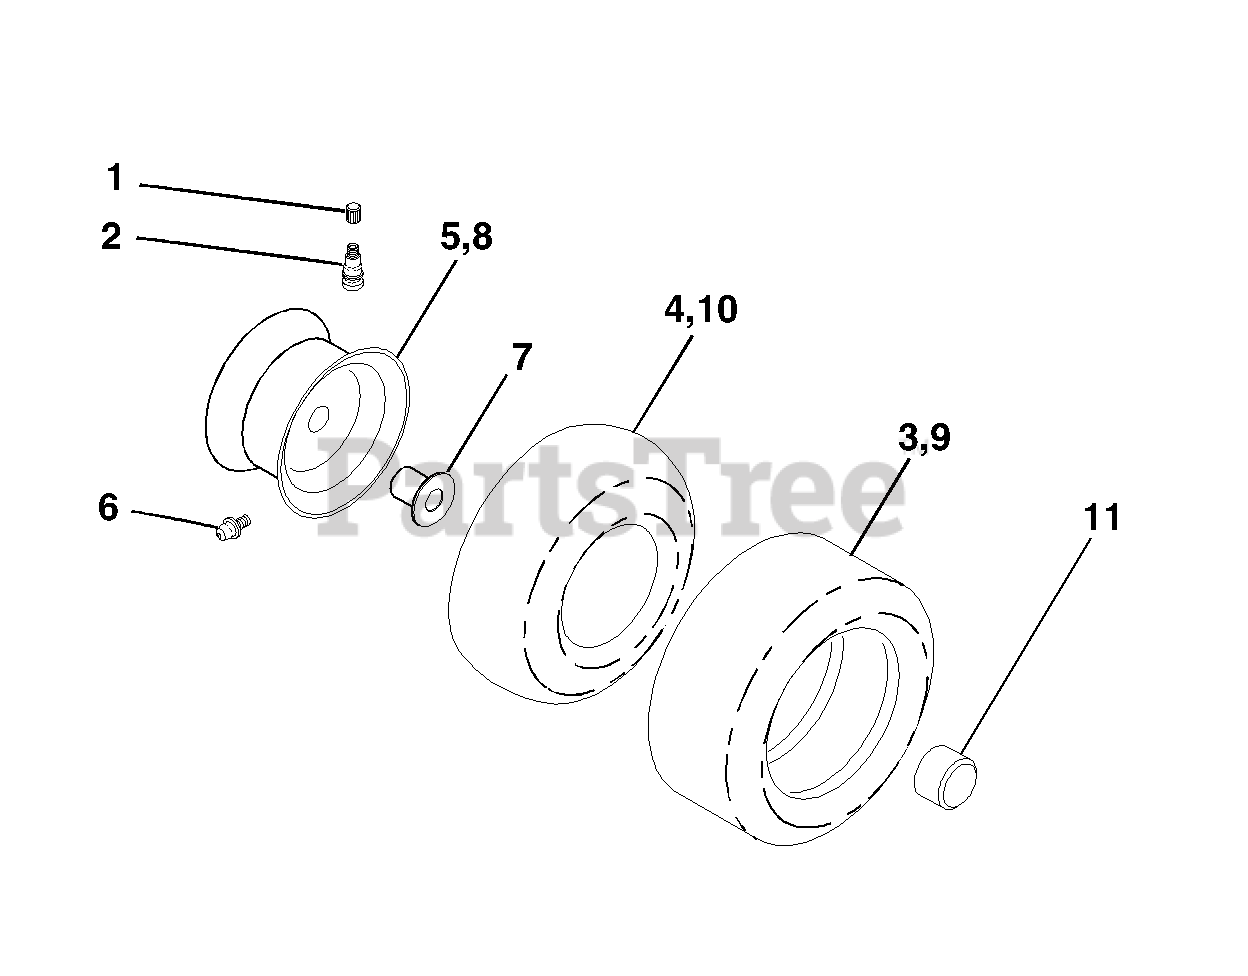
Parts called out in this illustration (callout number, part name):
1	Cap Valve Tire
2	Stem Valve
3	Tire Front
4	Tube Front
5	Rim Asm 6" front
6	Fitting Grease
7	Bearing Flange
8	Rim Asm 12" rear
9	Tire R 23 x 9.5-12 C Service
10	Tube Rear
11	Cap Axle Blk 1 50 X 1 00
